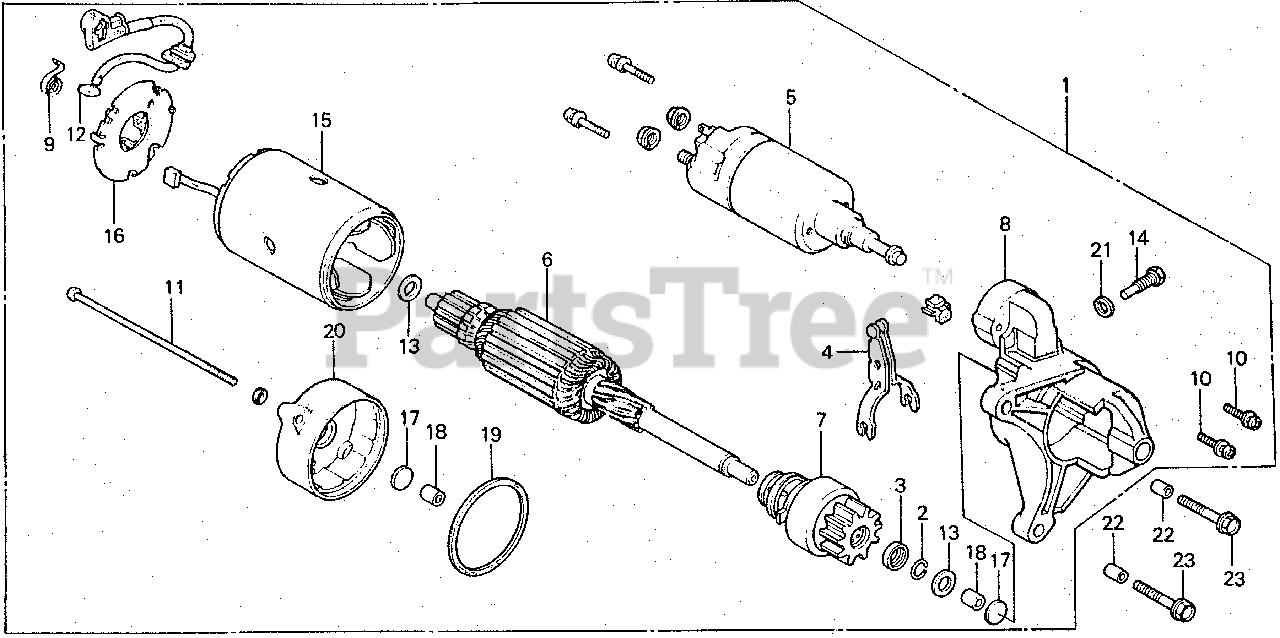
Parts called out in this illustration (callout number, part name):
1	MOTOR ASSY., STARTER
2	RING, SNAP (NOT AVAILABLE)
3	COLLAR, CLUTCH STOP
4	LEVER, PINION (NOT AVAILABLE)
5	SWITCH, MAGNETIC (NOT AVAILABLE)
6	ARMATURE (NOT AVAILABLE)
7	PINION
8	CASE, GEAR
9	SPRING, BRUSH (NOT AVAILABLE)
10	SCREW, MAGNETIC SWITCH SETTING
11	BOLT, THROUGH
12	BRUSH (NOT AVAILABLE)
13	WASHER
14	SCREW, ARMATURE SETTING
15	COIL, FIELD
16	HOLDER, BRUSH
17	COVER, BEARING
18	BUSH, BEARING
19	GASKET, RUBBER PLATE
20	COVER, RR.
21	WASHER, SPRING (8MM)
22	PIN, DOWEL (10X16)
23	BOLT, FLANGE (8X35)
